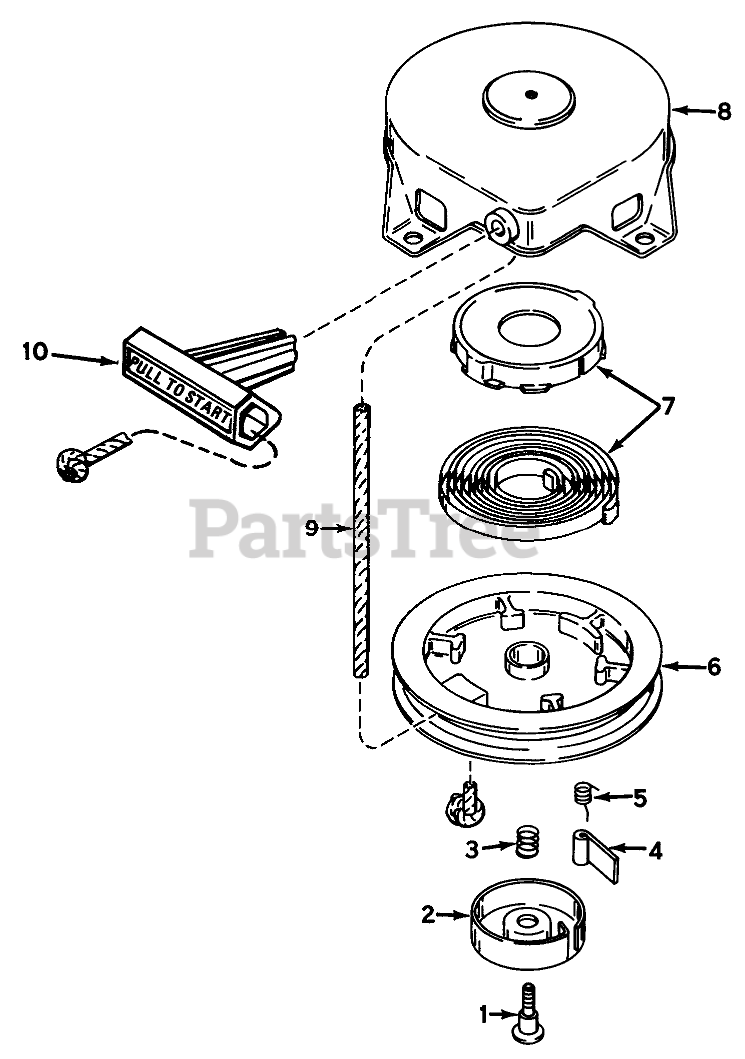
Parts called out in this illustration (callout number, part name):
2	Retainer
3	Spring-Brake
4	Dog-Starter
5	Spring-Dog
7	Spring & Keeper Assy
8	Housing-Starter
9	Rope-Starter (98 cut to length)
10	Handle-Starter
